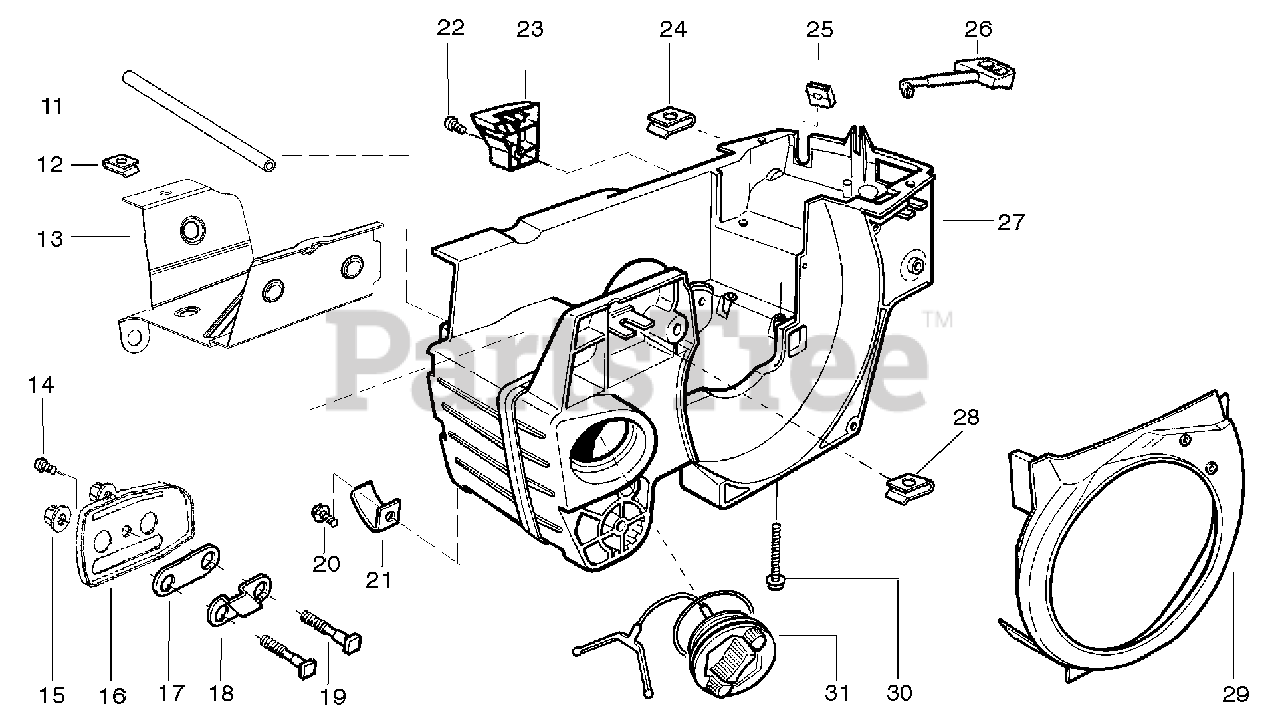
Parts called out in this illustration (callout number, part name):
11	Tube-Oil Vent
12	Retainer
13	Shield-Heat
14	Screw
17	Gasket-oil tank
18	Plate-Bar Stud
21	Chain Catcher
23	Cover- Limiter
24	Nut-Type "U" Speed
25	Grommet-Choke
26	Lever-Choke
27	Kit - Chassis Ass’y.
28	Nut-Type "U" Speed
29	Plate-Baffle
31	Assy.- Oil Tank Cap
